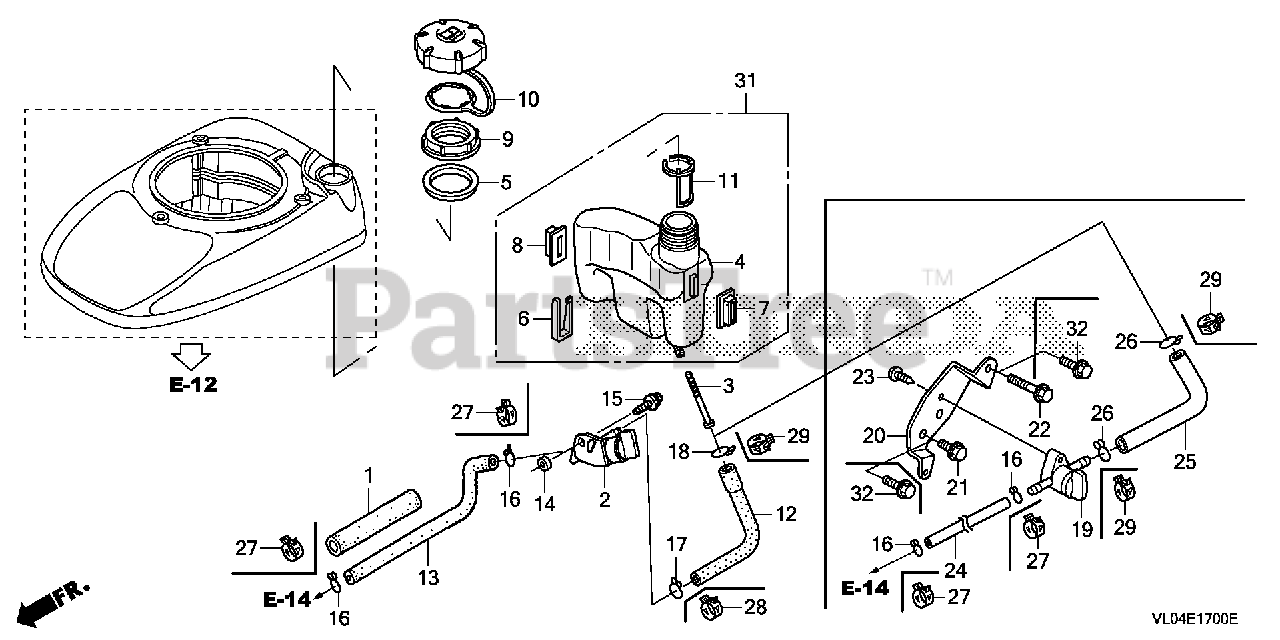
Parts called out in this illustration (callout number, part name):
3	FILTER, FUEL
4	TANK, FUEL
5	SEAL, FUEL FILLER NECK
7	RUBBER A, TANK MOUNTING
8	RUBBER B, TANK MOUNTING
9	NUT, TANK MOUNTING
10	CAP ASSY., FUEL TANK
11	GAUGE, FUEL LEVEL
16	CLIP, TUBE (C9)
19	PETCOCK ASSY.
20	STAY, PETCOCK
21	BOLT, FLANGE (6X12) (CT200)
22	BOLT, FLANGE (6X28) (CT200) Use up to Engine SN 1530314.
23	SCREW, TAPPING (5X12) (PO)
24	TUBE, FUEL (4.5X110)
25	TUBE, FUEL (7.3X160)
26	CLIP, TUBE (B12.5)
